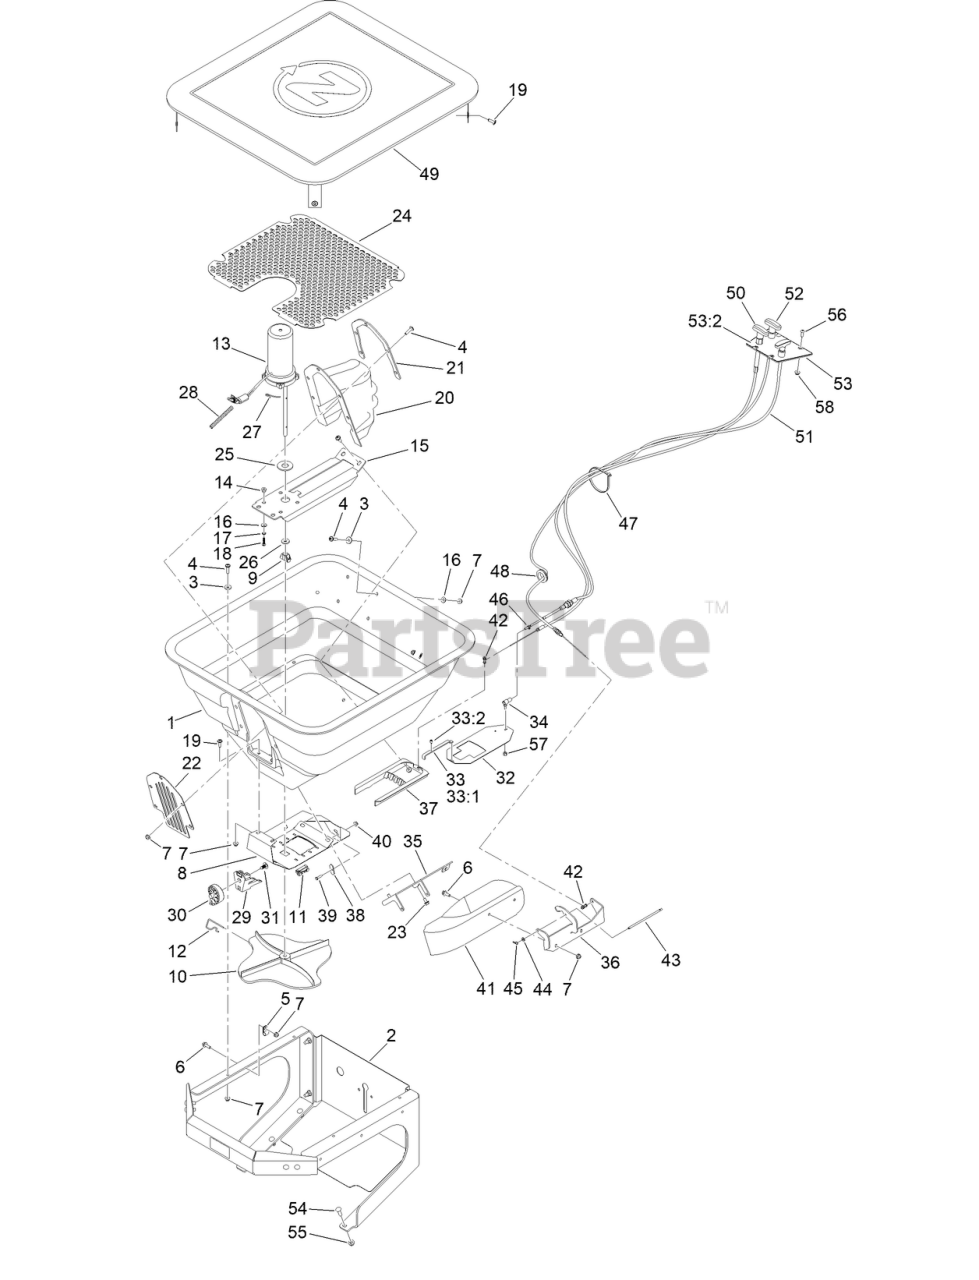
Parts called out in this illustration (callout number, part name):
1	HOPPER -150 LB
2	Hopper Frame ASM
4	Screw-Hsbhf
5	CLAMP-R
6	Screw-HHF
7	Nut-Hex Flange
8	BASE PLATE, HOPPER, 140
9	HOPPER BOTTOM BEARING
10	Spinner-Spreader
11	GUIDE-RATE, GATE
12	Clip-Spinner
13	MOTOR-SPREADER
14	SPACER-FLANGED
15	BRACKET-MOUNT, MOTOR
16	WASHER-FLAT
17	WASHER-LOCK, INT
18	SCREW-SHWH
19	Screw-Hsbhf
20	COVER-MOTOR
21	FLANGE-COVER, MOTOR
22	COVER-FRONT, MOTOR
23	SCREW-HWH
24	SCREEN-HOPPER, MEDIUM
26	WASHER-FELT
27	WIRE-AGITATOR
28	LOOM-SPLIT
29	MOUNT-DIAL
31	Footpad Fastener
32	SLIDE-DOOR, HOPPER
33	RATE GATE LINK ASM
33:1	LINK-GATE, RATE
33:2	SCREW-SHOULDER, SLOTTED
34	BALL JOINT-SS
35	MOUNT-DEFLECTOR, SIDE
36	BRACKET-DEFLECTOR, SIDE
37	DIFFUSER
38	RETAINER, CABLE
39	SCREW-HH
40	Nut-Hex Flange
41	Screw-HH 1/4-20 X 7/8 SS
42	WIRE-STOP
43	PIN-DEFLECTOR SS
44	WASHER-FLAT
45	PIN-COTTER, HAIR
46	Nut,Hex Jam Mch Scr,10-32,Sst
47	TIE-CABLE
48	GROMMET
49	COVER-HOPPER, CLEAR VINYL WINDOW
50	CABLE-PUSH/PULL
51	CABLE PUSH/PULL
52	CABLE PUSH/PULL
53	Spreader Control Panel ASM W/Decal
53:2	DECAL-SPREAD CABLE
54	Bolt,Carriage,5/16-18X1,ST/ST 18-8
55	Nut-Hex Flange
56	SCREW-HWH
57	Nut,NYL Lock,#10-32,ST/ST 18-8
